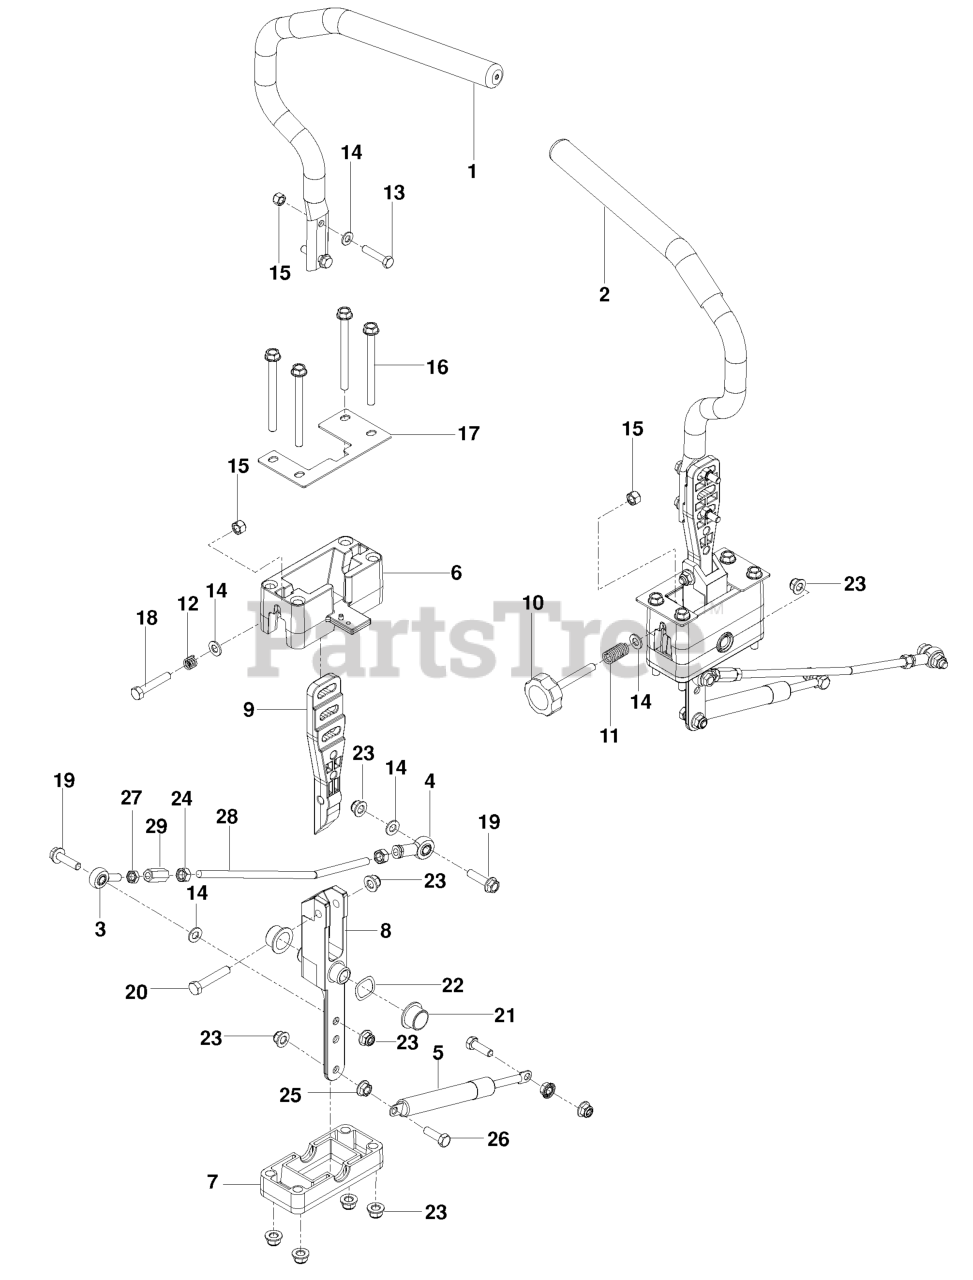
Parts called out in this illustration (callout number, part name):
1	LEVER.DRIVE.W/GRIP.RIGHT
2	LEVER.DRIVE.W/GRIP.LEFT
3	RP.ROD.END.LH
4	RH ROD END
6	BLOCK, UPPER
7	BLOCK, LOWER
8	PIVOT.SECTION.DRIVE.CONTROL
9	MOUNT, DR CNTRL HANDLE
10	KNOB
13	CAPSCREW 5/16 X 1/1/2 HEX HEAD
14	FLAT WASHER 5/16 SAE
15	NUT 5/16 NYLOC
16	HHFS 5/16-18 X 3 3/4
17	PLATE, NEUTRAL STOP, BLACK
18	HCS 5/16-18X1-3/4 TPBLT
19	HHFS 5/16-18 X 1.25 TPBLT GD 5
20	HCS 5/16C X 1 3/4
21	BEARING, FLANGE
22	WASHER, .825 X 1.087, WAVE
23	5/16-18 NYLOC FLANGE NUT
25	NUT 5/16C WHIZ
26	HCS 5/16C X 1
27	NUT 5/16F LEFTHAND
28	ROD, CONTROL
29	ROD END COUPLER
